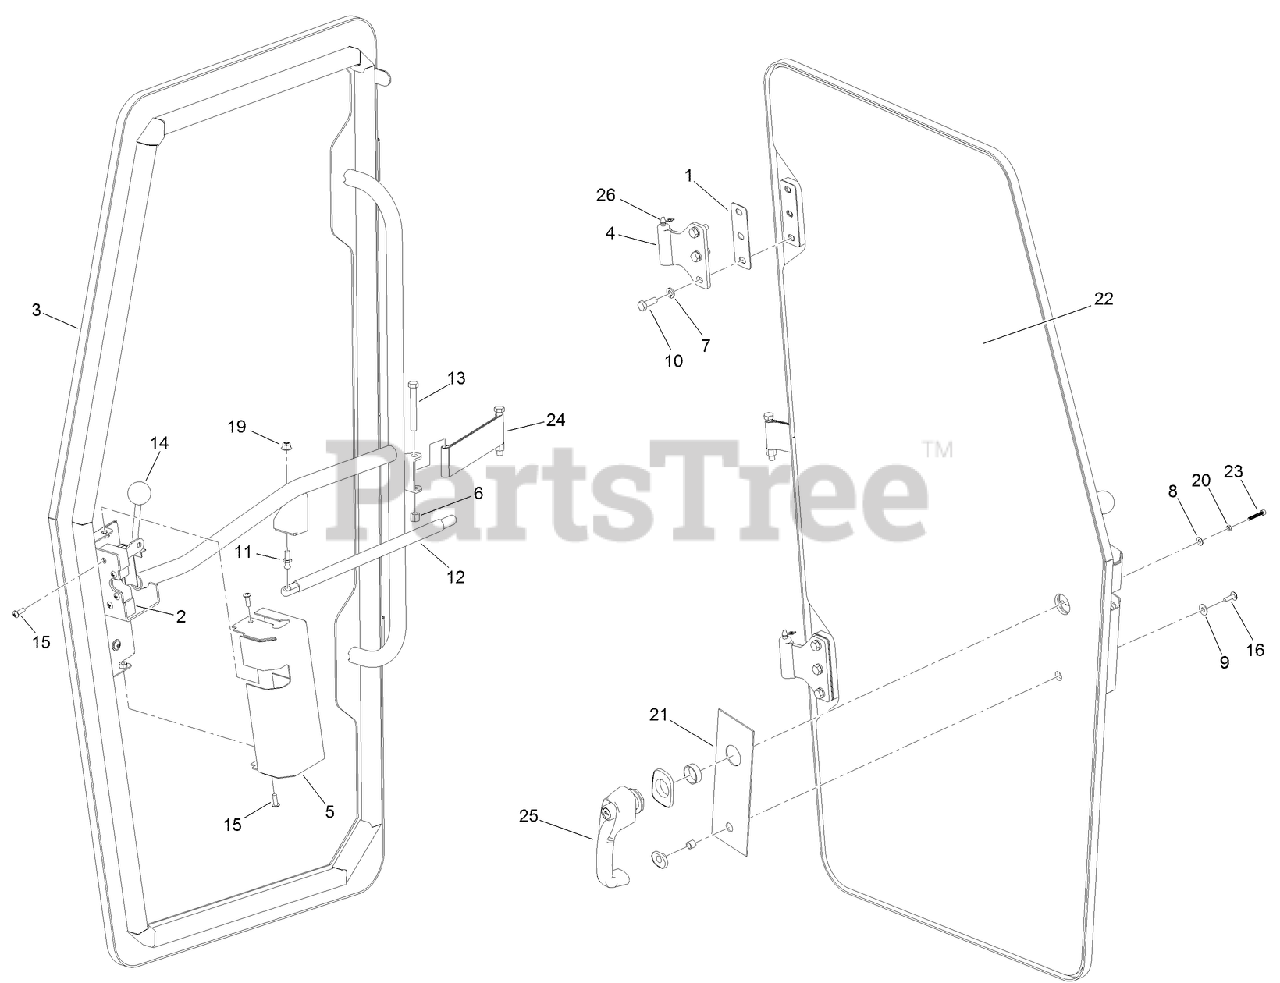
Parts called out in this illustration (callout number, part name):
1	SHIM-HINGE, DOOR
3	DOOR-RH
4	HINGE-DOOR, RH
5	COVER-LATCH RH
7	WASHER-LOCK
8	WASHER-FLAT
9	WASHER-FLAT
10	BOLT-HHCS
11	STUD-BALL, GAS SPRING
12	SPRING-GAS
13	BOLT-HHCS
19	NUT-HEX
20	NUT-M5
21	GASKET-HANDLE, DOOR
22	GLASS-DOOR, RH
23	BOLT-SHCS
24	STRAP-HOLDER, DOOR
25	HANDLE-EXTERIOR
26	CAP-GREASE, ZERK
